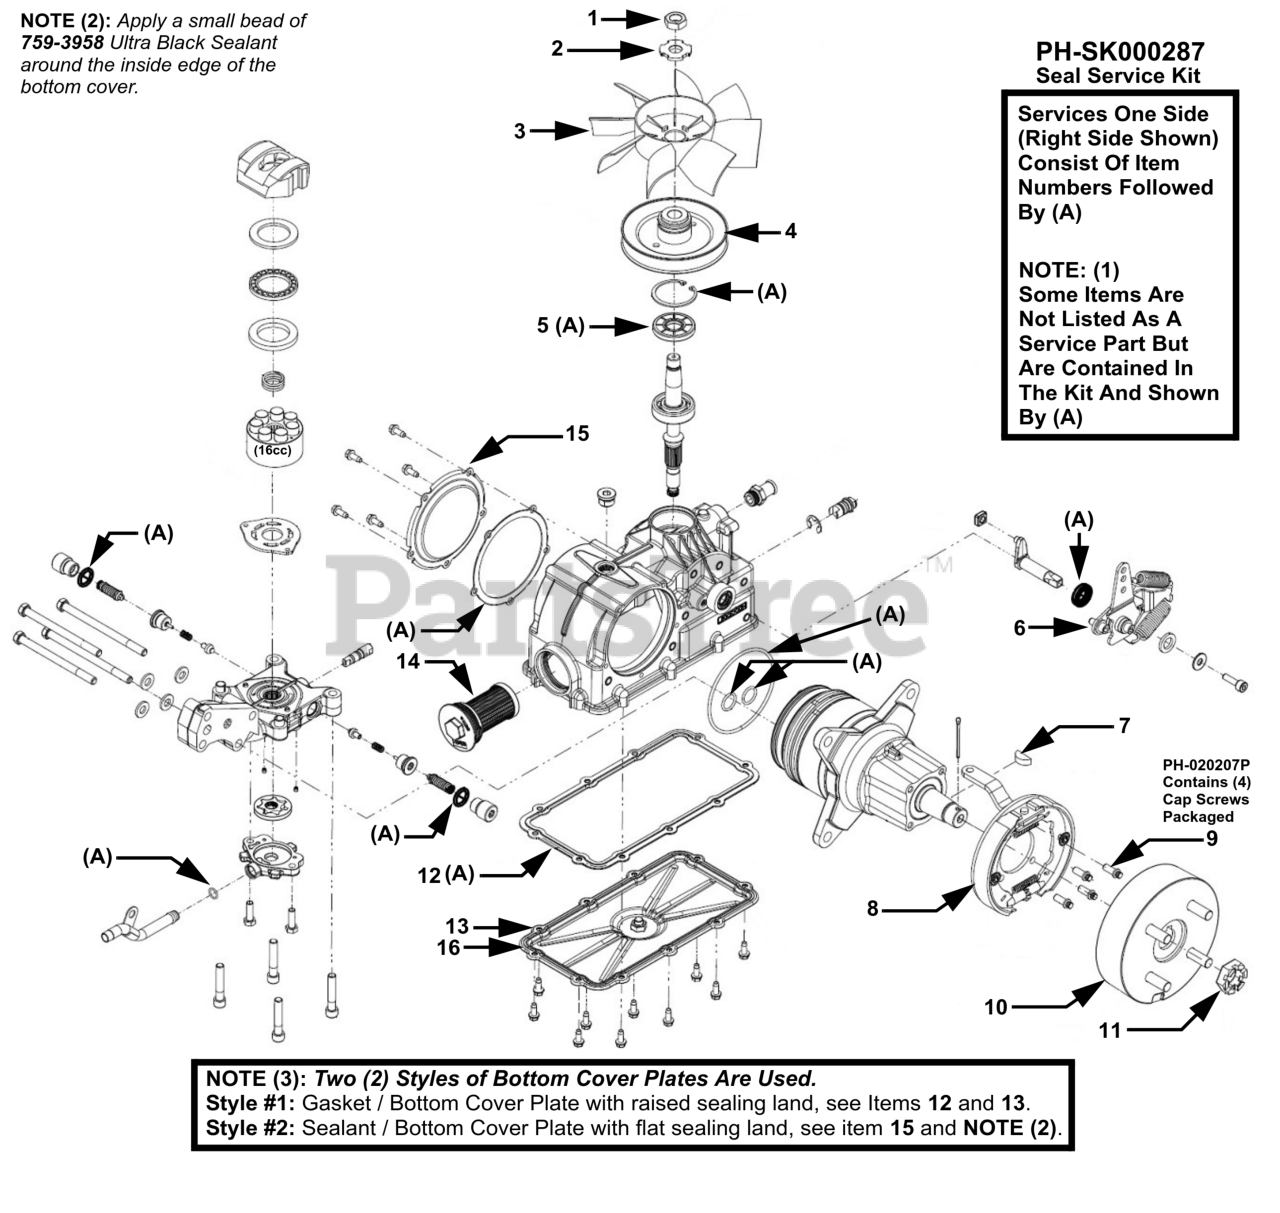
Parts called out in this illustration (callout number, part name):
6	SERVICE KIT
7	WOODRUFF KEY
8	BRAKE ASSEMBLY-ON HOLE LEVER
9	SCREW-CAP (QTY 4)
10	DRUM-4 BOLT BRAKE
11	NUT-SLOTTED
12	BOTTOM COVER GASKET
13	BOTTOM COVER
15	SIDE COVER PLATE
16	BOTTOM COVER
A	SEAL SERVICE KIT
